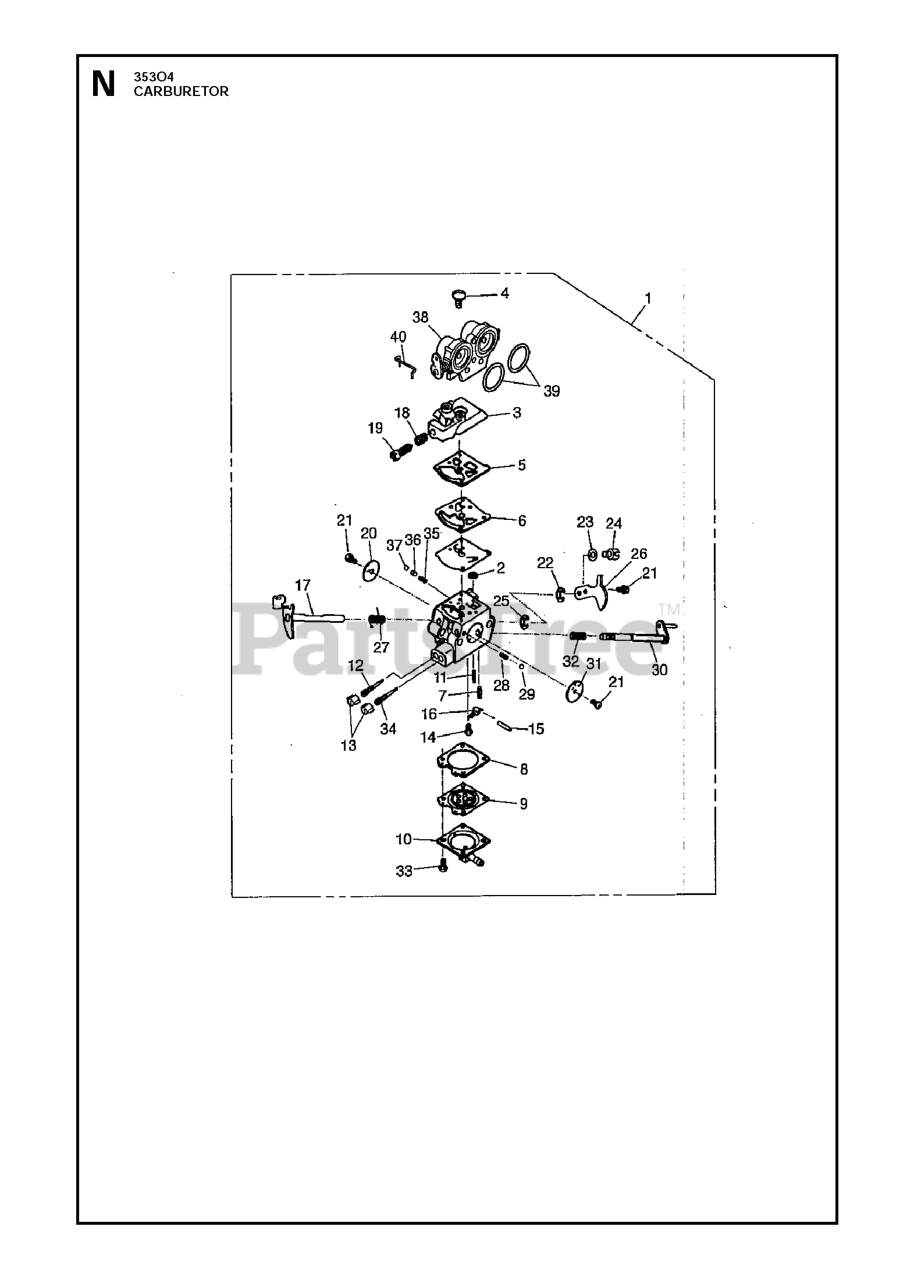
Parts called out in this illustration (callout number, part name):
2	SCREEN
7	VALVE INLET
26	LEVER, THROTTLE
27	SPRING RETURN
28	CHOKE SPRING
30	SHAFT, CHOKE
31	ACCELATOR
33	SCREW ASSY
36	PISTON
37	BALL
